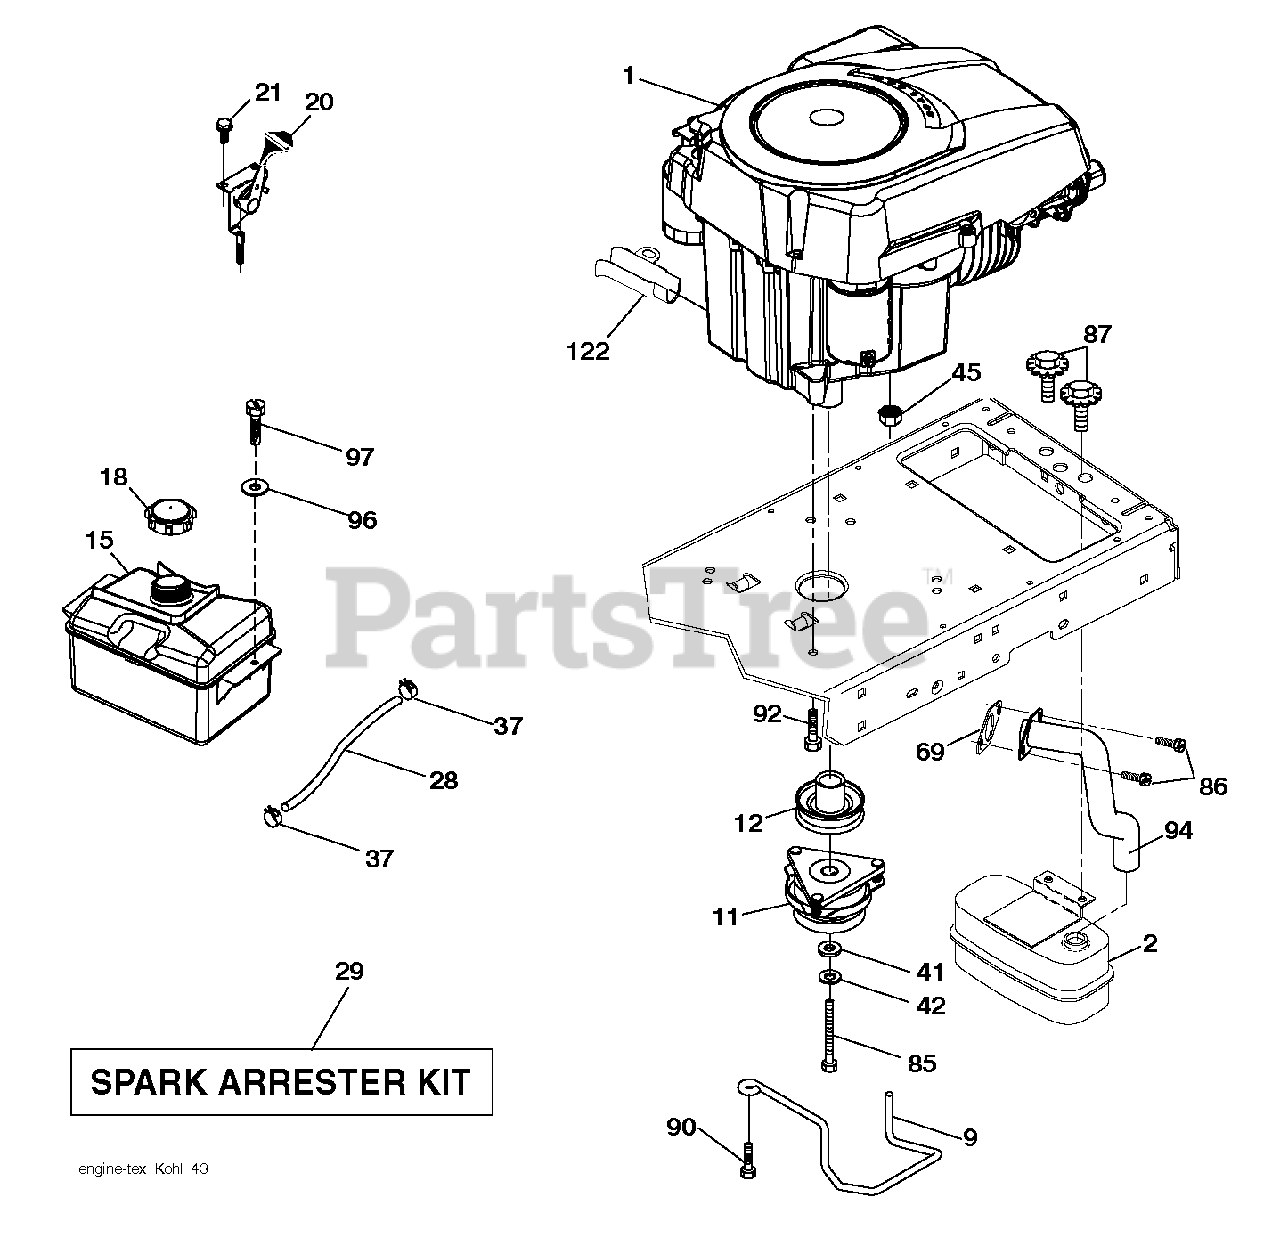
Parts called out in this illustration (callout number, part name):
2	MUFFLER.SINGLE.LRG.BRIGGS.KOHL
9	KEEPER BELT ENGINE
11	CLUTCH.ELECTRIC.LT.48"*
12	PULLEY.ENGINE.TUFFTORQ
15	FUEL.TANK.ASM.NON-EPA
18	CAP ASM.FUEL.2.25"FR.
20	CONTROL.TH/CK.C.
21	SCREW.#10 X 0.750.BOS
28	LINE.FUEL.20
29	KIT.SPARK ARRESTOR 794945 B&S
37	HOSE CLAMP
42	LOCKWASHER
45	NUT
69	GASKET.EXHAUST.KOHLER
85	BOLT HEX 7/16-20X4-1/4"
86	SCREW.SOCKET HD.5/16-1
87	BOLT, 5/16-18 X 1 3/4
90	SCREW 3/8-16X1
92	SCREW 3/8-16X1
94	TUBE.EXHAUST.KOHLER.COURAGE
97	SCREW HEXWSHR 1/4-20X3/4
122	EXTENSION DRAIN OIL
